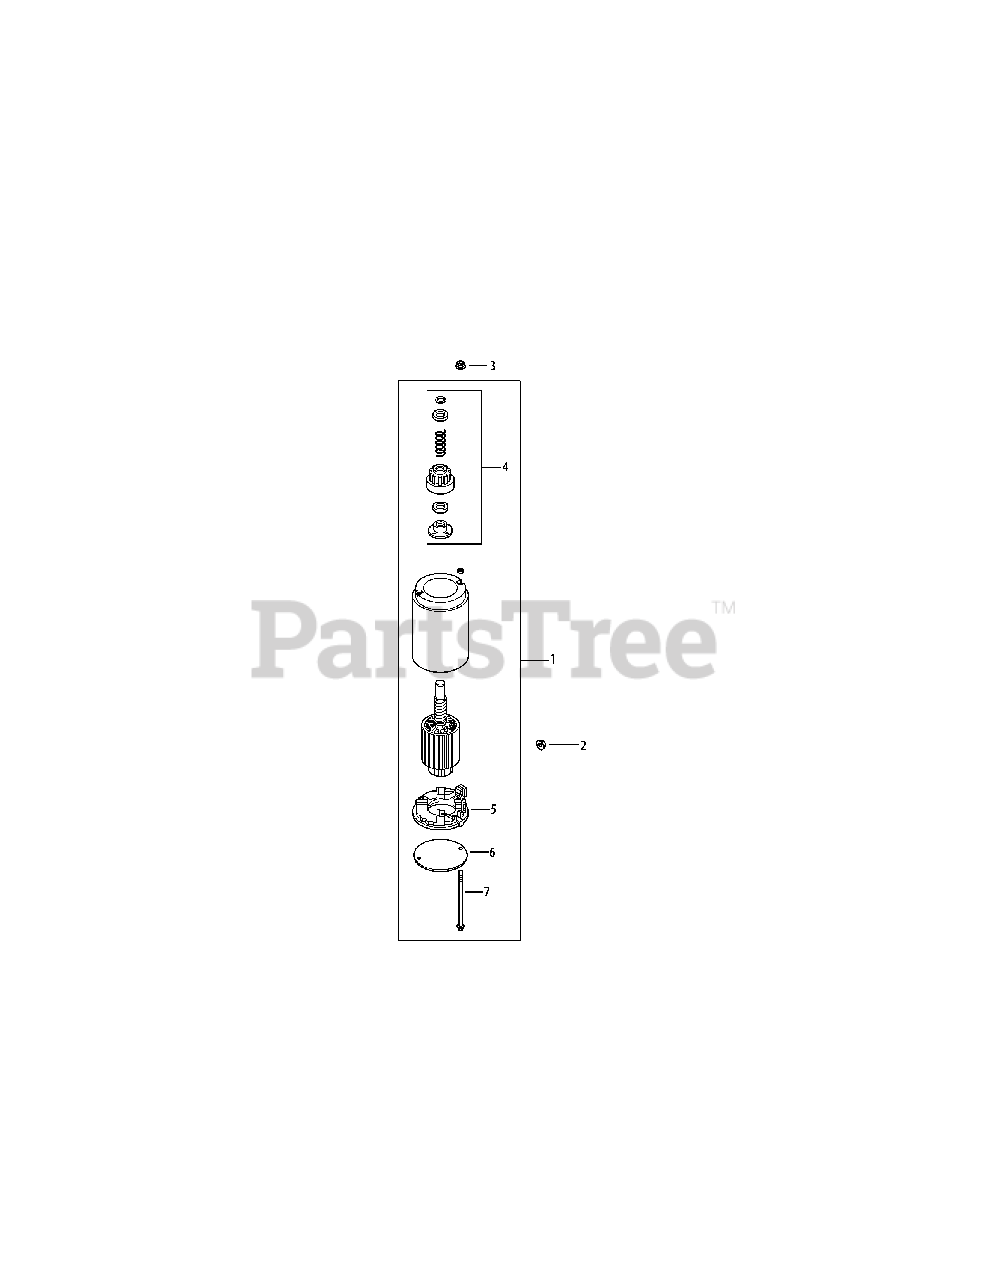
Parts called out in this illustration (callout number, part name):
1	Starter Assembly (Inc. 4-7)
3	Free Spinning Flg. Nut, #10-24
4	Drive Kit (J.E.)
6	Drive End Cap (J.E.)
